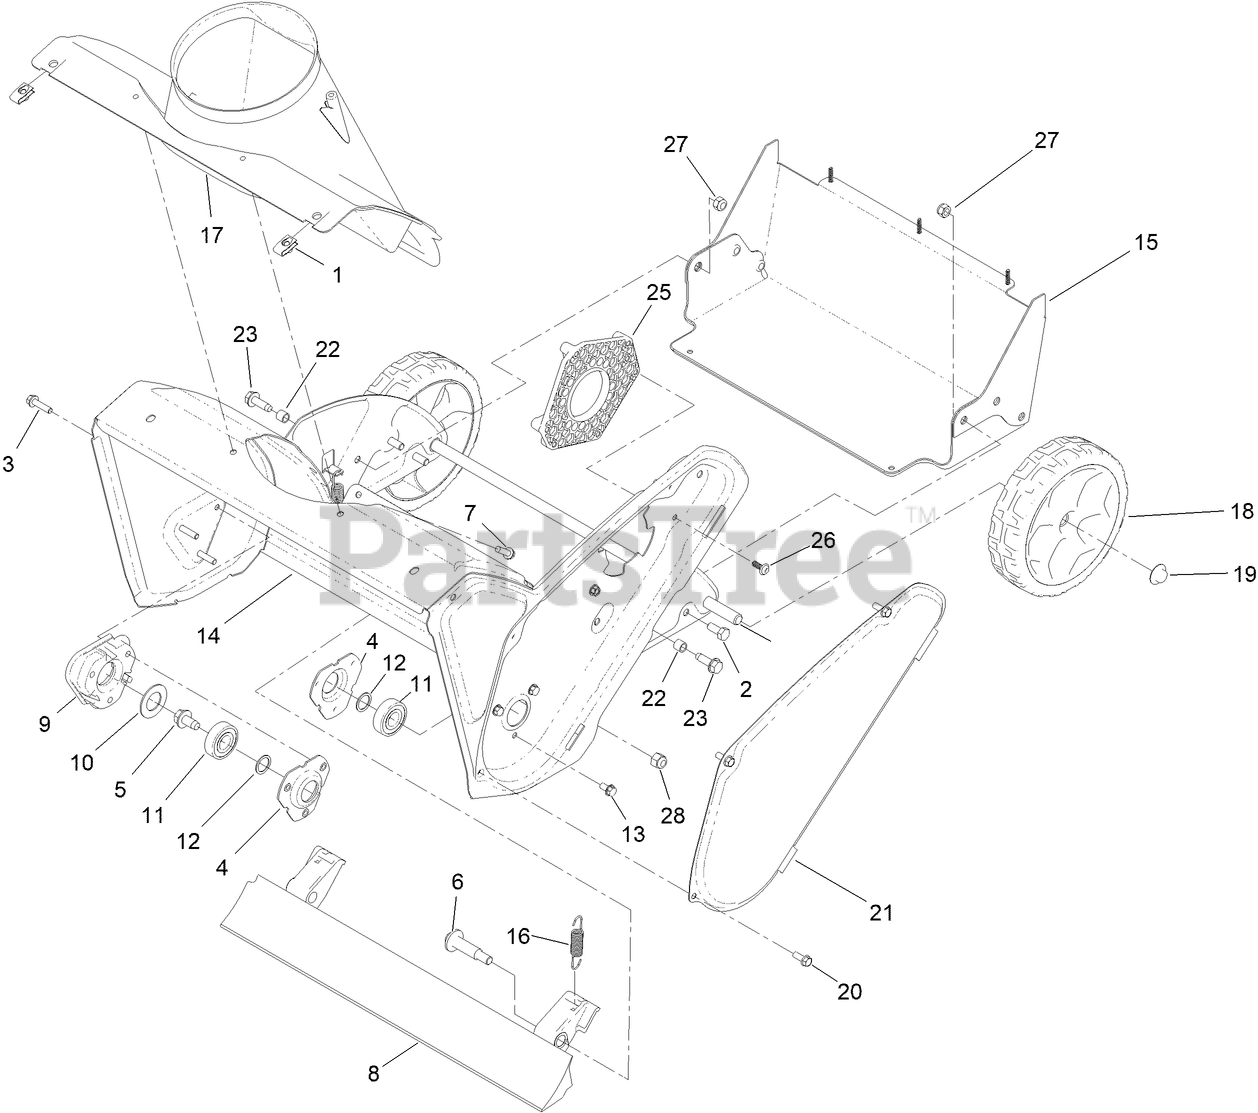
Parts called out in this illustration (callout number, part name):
2	SCREW-HH
3	SCREW-HWHTF
4	FLANGE-BEARING
5	SCREW-HWH
6	BOLT-SHOULDER
7	SCREW-HWH
8	BLADE-SCRAPER, PC21
9	SPACER-BEARING, RH
10	WASHER-RUBBER
11	BEARING-BALL
12	WASHER-THRUST
13	SCREW-HWH
14	HOUSING ROTOR, ASM [BLACK]
15	support, large
16	SPRING-EXTENSION
17	CHUTE-LOWER
18	WHEEL ASM, 7 INCH
19	NUT-PUSH
20	SCREW-HWH
21	COVER-BELT
22	SPACER-GROMMET
23	SCREW-HWHTF
25	MOUNT - MOTOR
26	SCREW-DELTA POINT
27	NUT-LOCK, NI
28	NUT-HEX
